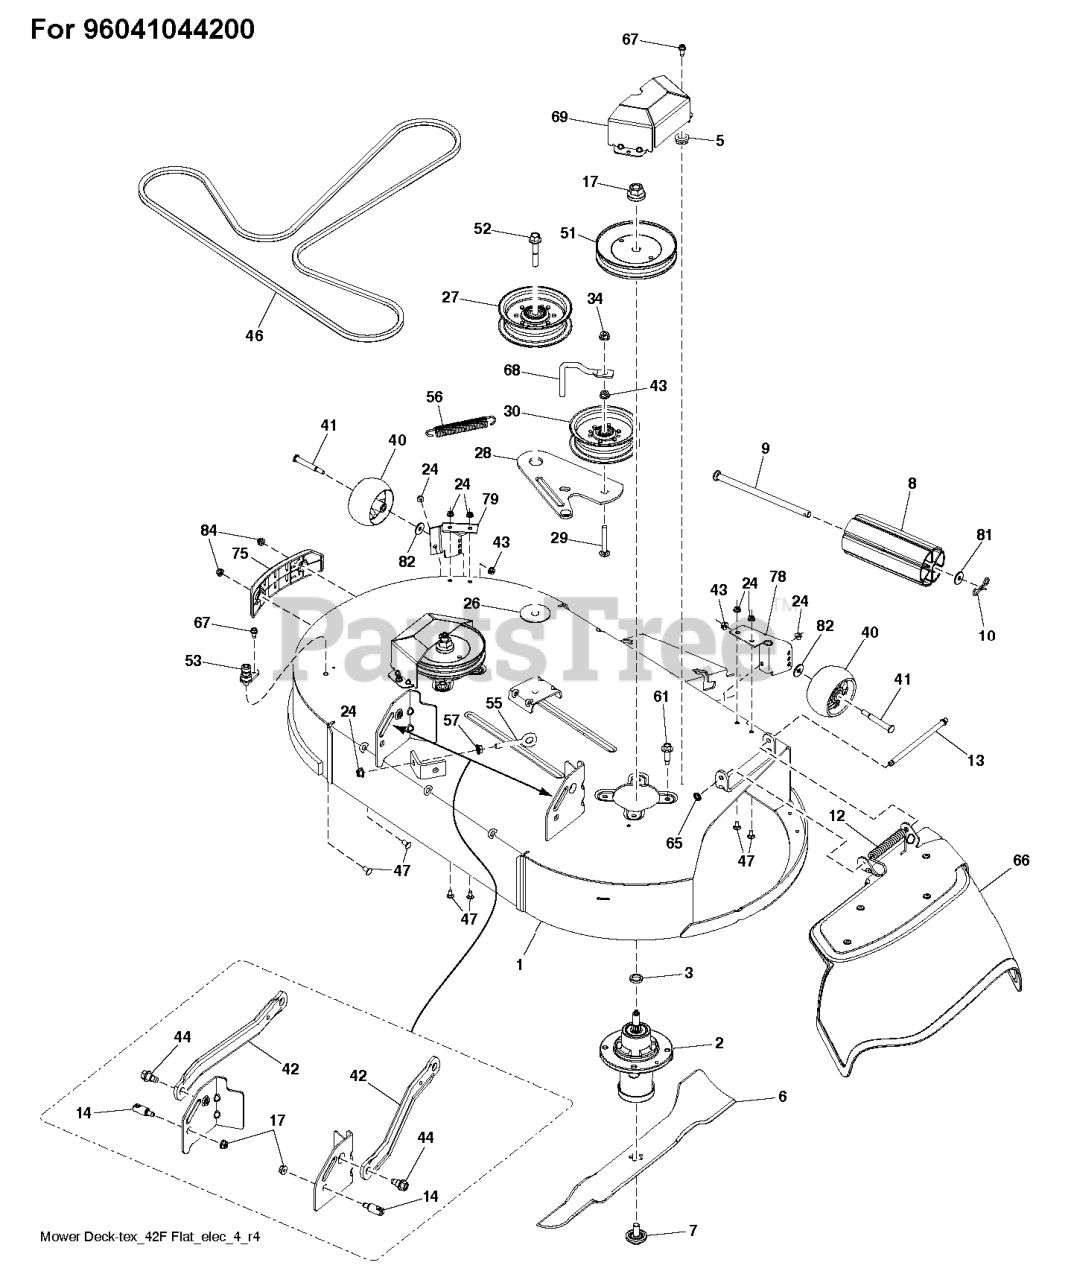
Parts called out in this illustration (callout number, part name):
1	DECK SVC.42F.668
2	MANDREL ASM, CAST IRON
3	WASHER.SPACER.MANDREL
6	BLADE.42.FCS.BAGGING.BLADE.
7	BOLT.WASHER.ASM.7/16-2
8	NOSE ROLLER 48"
10	PIN.COTTER.5/16.BOW TI
12	SPRING.42.FCS.DEFLECTOR
14	STUD.W/"D"ANTI-ROTATION
24	NUT HEXAGON FLANGE 5/16-18 ST
27	PULLEY.IDLER.MWR.STATI.LH
28	ARM.42"FCS.CLUTCHING.X431
30	PULLEY.IDLER.2006
40	WHEEL.GAUGE.RALLY
42	ARM.RFIXED.MOWER.SUSPNSIONX431
43	NUT LOCK FLG 3/8-16 UNC
44	BOLT.SHOULDER
46	BELT.42.FCS.TRACTOR.DECK.DRIVE
47	GSPW Bolts
51	PULLEY MANDREL 5.0"
52	SCREW.7/16-14 X 2.125.WASHER
53	PORT.WASHOUT
55	GSPW Bolts
56	SPRING.EXTN.42.FCS.TR.DECK.DRV
57	GSPW Hardware
61	BOLT.HEX.WASHR.HED.313-18X1.19
65	NUT PUSH M
66	DEFLECTOR.ASM.42.FCS.ORANGE
67	SCREW.1/4-20X5/8
68	KEEPER.BELT.IDLER.54"T
69	COVER.42".MANDREL.FCS.PNT.498
75	BUMPER.42CC.TRIM.SIDE.ASSY.HUS
78	BRACKET.PNT.GA-WHEEL.FCS.42.RH
79	BRACKET.PNT.GA-WHEEL.42FCS.LH
81	BUSHING.NOSE.ROLLER
84	SHOULDER BOLT 5/16-18TT
